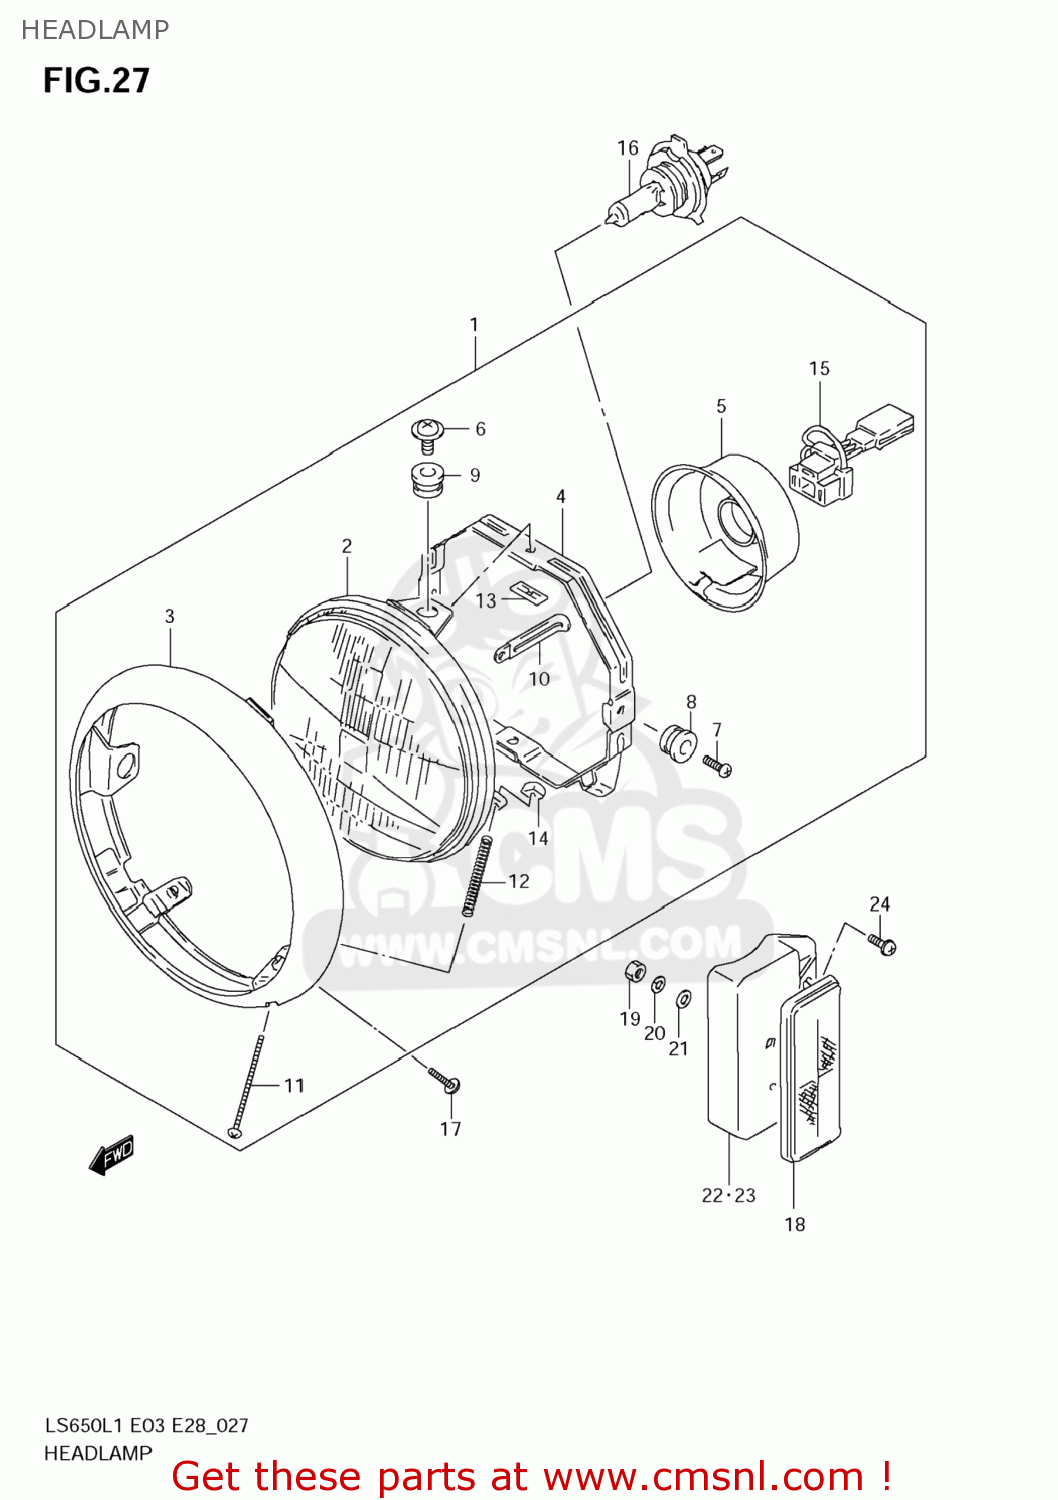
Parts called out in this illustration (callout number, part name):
1	HEADLAMP ASSY
2	UNIT,LAMP
3	RIM
4	RING,MOUNTING
5	COVER
6	SCREW
7	SCREW,MOUNTING
8	CUSHION
9	CUSHION
10	CLAMP(L:65)
11	SCREW,ADJUSTING(4X50)
12	SPRING
13	NUT
14	NUT,HEADLAMP ADJUST
15	SOCKET
16	BULB(12V60/55W,H4)
17	SCREW
18	REFLEX REFLECTOR,FR SIDE
19	NUT
20	WASHER,LOCK
21	WASHER(5.5X16X1.2)
22	BRACKET,FR SIDE RR,R
23	BRACKET,FR SIDE RR,L
24	SCREW(5X12)
